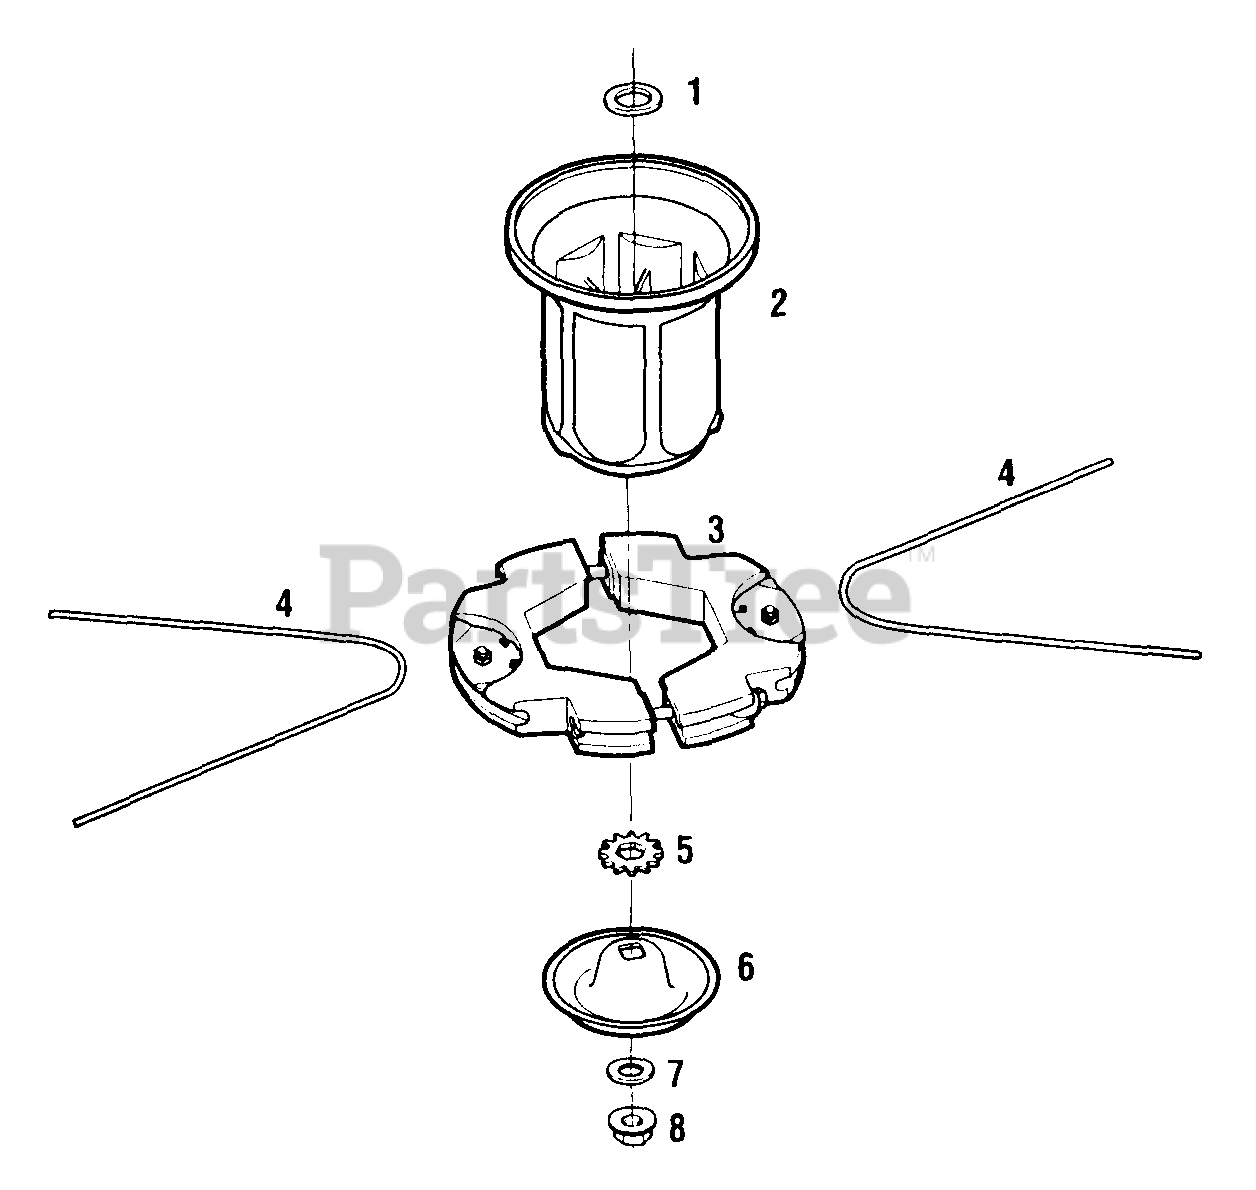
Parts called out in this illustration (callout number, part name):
1	Shoulder Washer
2	Spindle Head
3	Trimmer Head
4	Trimmer String
5	Hex Spline Washer
6	Wear Cup
7	Washer
8	Hex Flange Nut, 1/2-13
